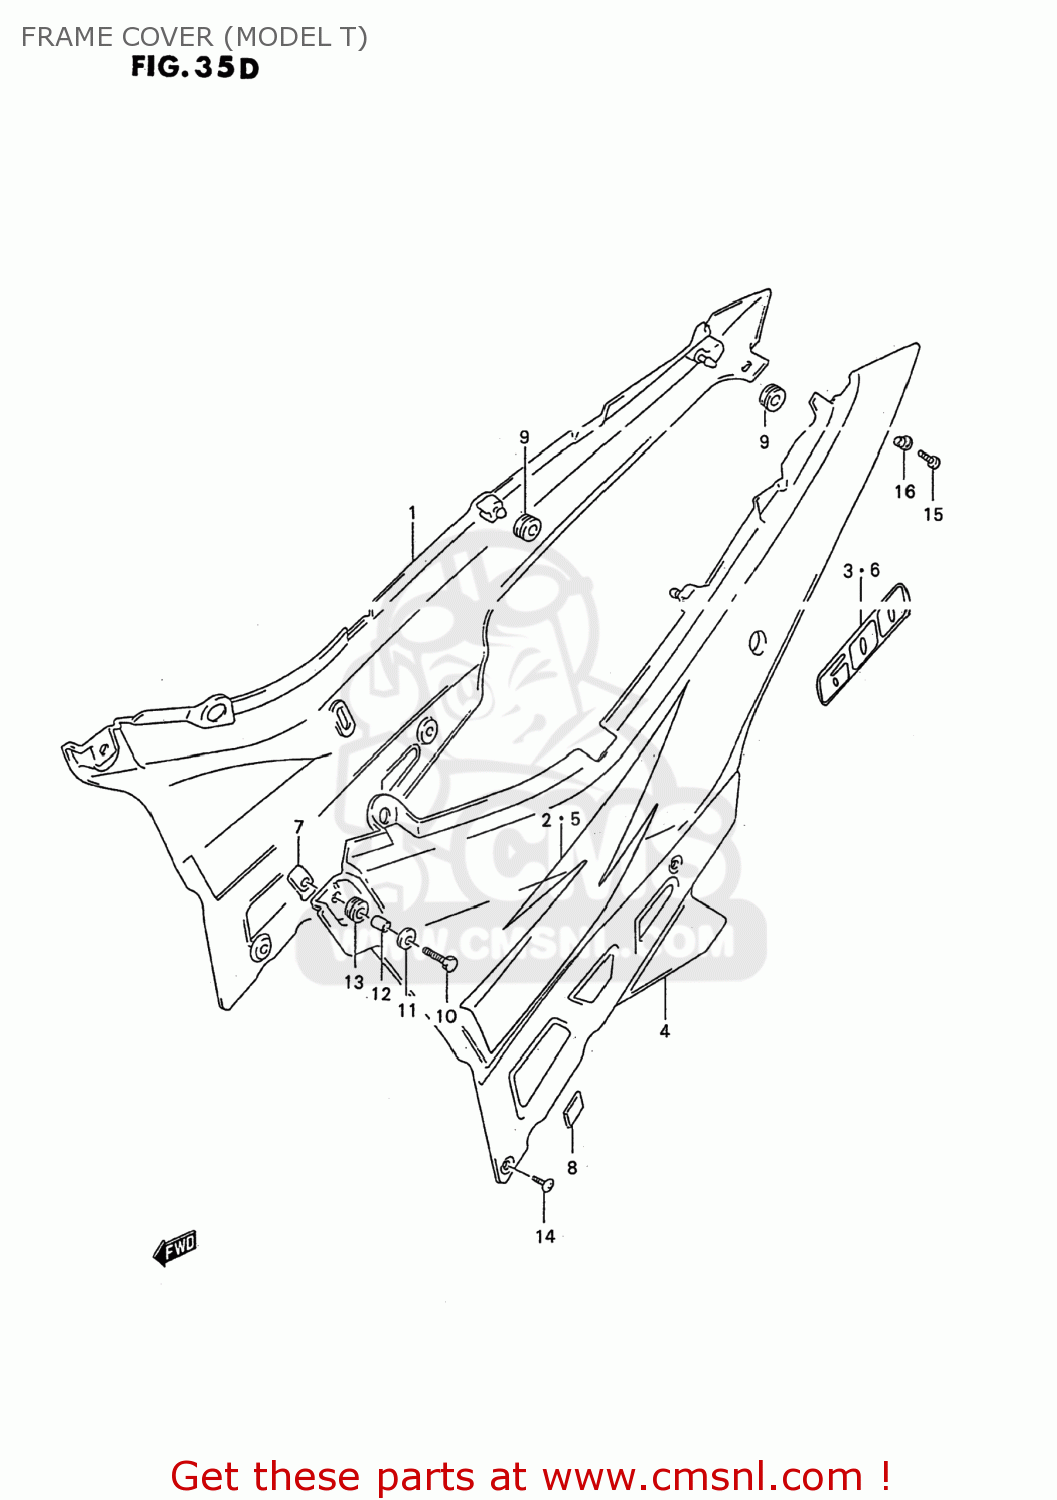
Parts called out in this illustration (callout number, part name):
1	COVER,FRAME,R
2	TAPE,FRAME COVER,R
3	EMBLEM,FUEL COVER
4	COVER,FRAME,L
5	TAPE,FRAME COVER,LEFT
6	EMBLEM,FUEL COVER
7	PLATE,FRAME COVER
8	CUSHION,FRAME COVER
9	CUSHION
10	SCREW(6X20)
11	WASHER
12	SPACER (6.1X9X9)
13	CUSHION
14	SCREW(5X15.3)
15	SCREW 5X12
16	WASHER
